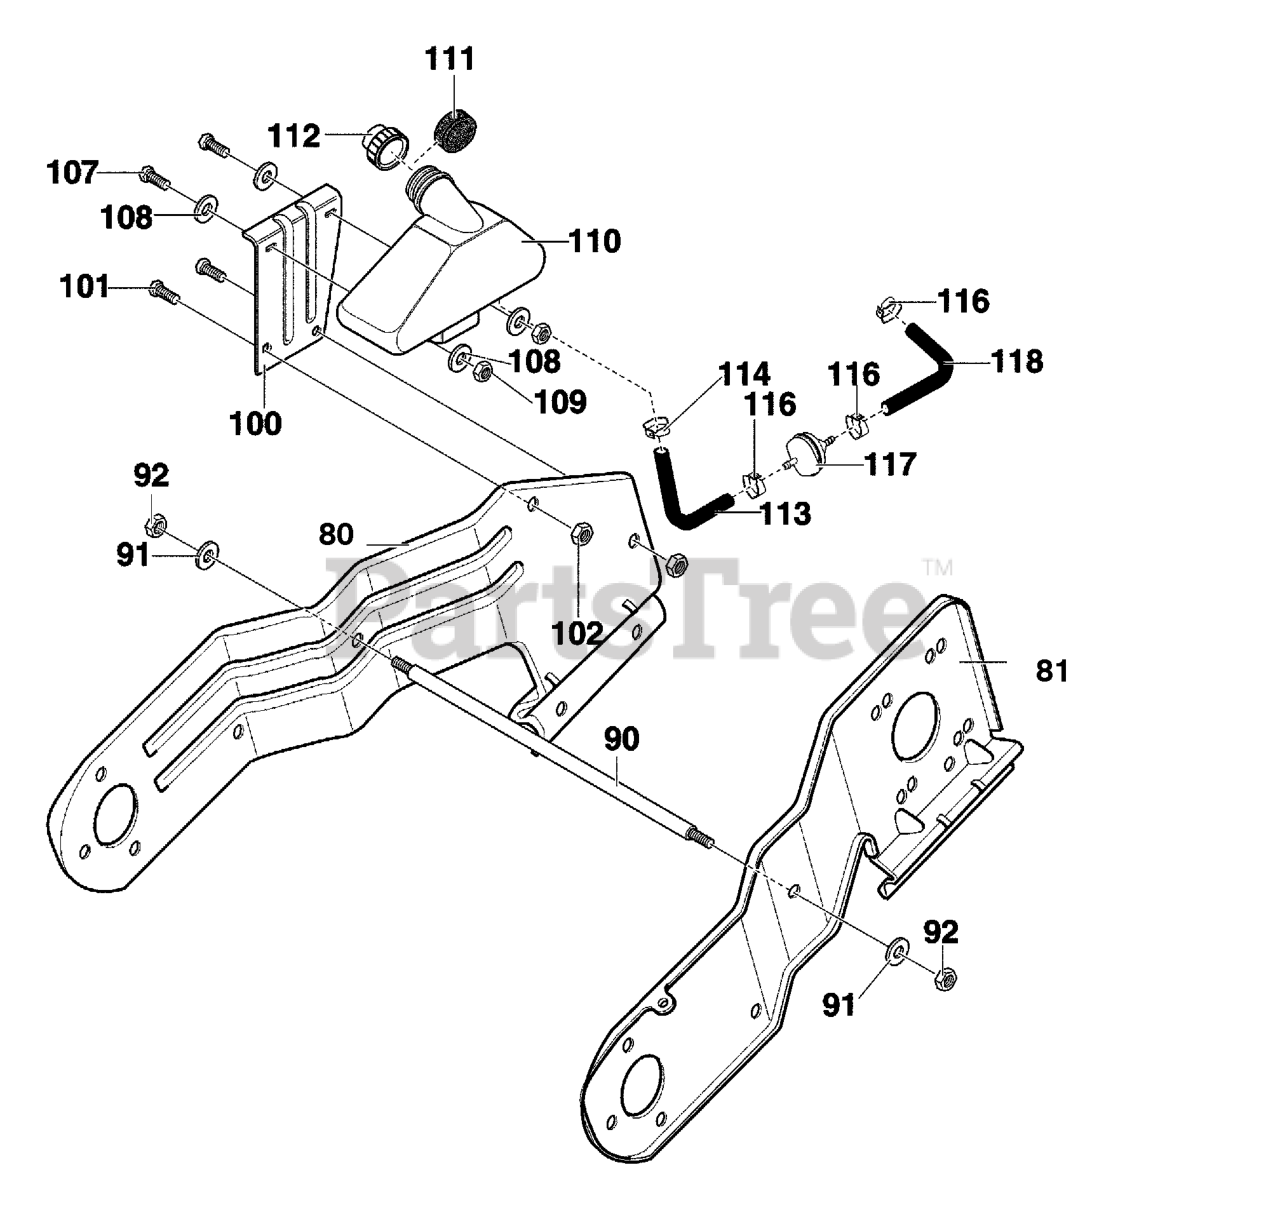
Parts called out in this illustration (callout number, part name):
80	FRAME, SIDE SUPT STEEL RH
81	FRAME, SIDE SUPT STEEL LH
90	ROD, SUPPORT
91	WASHER, HVSPTLK
92	NUT, 3/8-16 REGHEX
100	BRACKET, GAS TANK
101	SCREW, 1/4-20X.75
102	NUT, 1/4-20 REGHEXCTRLK
107	SCREW, 1/4-20X.75
108	WASHER, FLAT
109	NUT, 1/420 REGHEXCTRLK
110	TANK, FUEL
111	RING, FOAM FUEL TANK
112	CAP, GAS
113	TUBING 8 IN.
114	CLAMP, HOSE SCREW
116	CLAMP, HOSE
117	FILTER IN LINE
118	TUBING, 6 IN.
